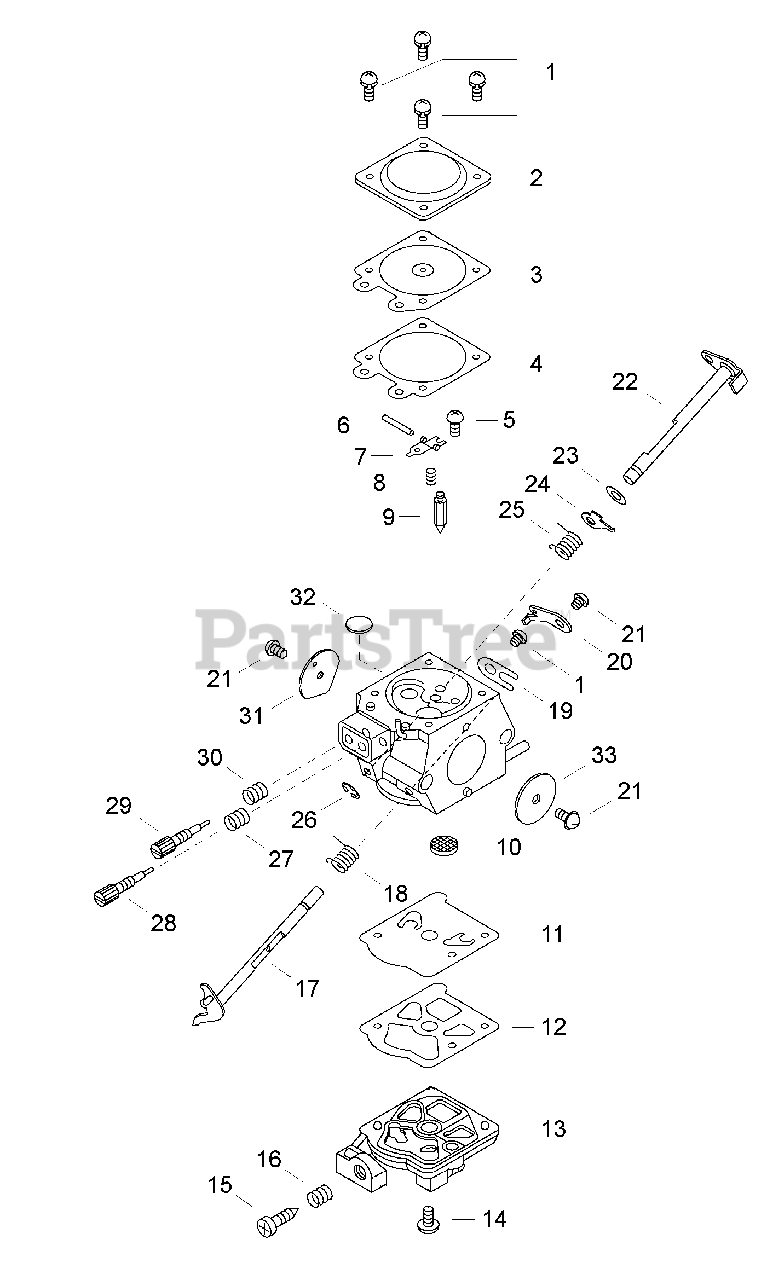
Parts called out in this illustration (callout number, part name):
2	COVER, METERING DIAPHRAGM
3	DIAPHRAGM, METERING
4	GASKET, METERING DIAPHRAGM
5	SCREW, METERING LEVER PIN
6	PIN, METERING LEVER
7	LEVER, METERING
8	SPRING, METERING LEVER
9	VALVE, INLET NEEDLE
10	SCREEN, FUEL INLET
11	GASKET, FUEL PUMP
12	DIAPHRAGM, PUMP
13	COVER, FUEL PUMP
15	SCREW, IDLE ADJUST
16	SPRING, IDLE ADJUST
17	SHAFT, THROTTLE
18	SPRING, THROTTLE RETURN
19	CLIP, THROTTLE SHAFT
20	LEVER, THROTTLE
22	SHAFT, CHOKE
24	LEVER, FAST IDLE
25	SPRING, CHOKE RETURN
27	SPRING, HIGH NEEDLE
28	NEEDLE, HIGH SPEED
29	NEEDLE, LOW SPEED
30	SPRING, NEEDLE
31	VALVE, CHOKE
32	PLUG, WELCH
33	VALVE, THROTTLE
